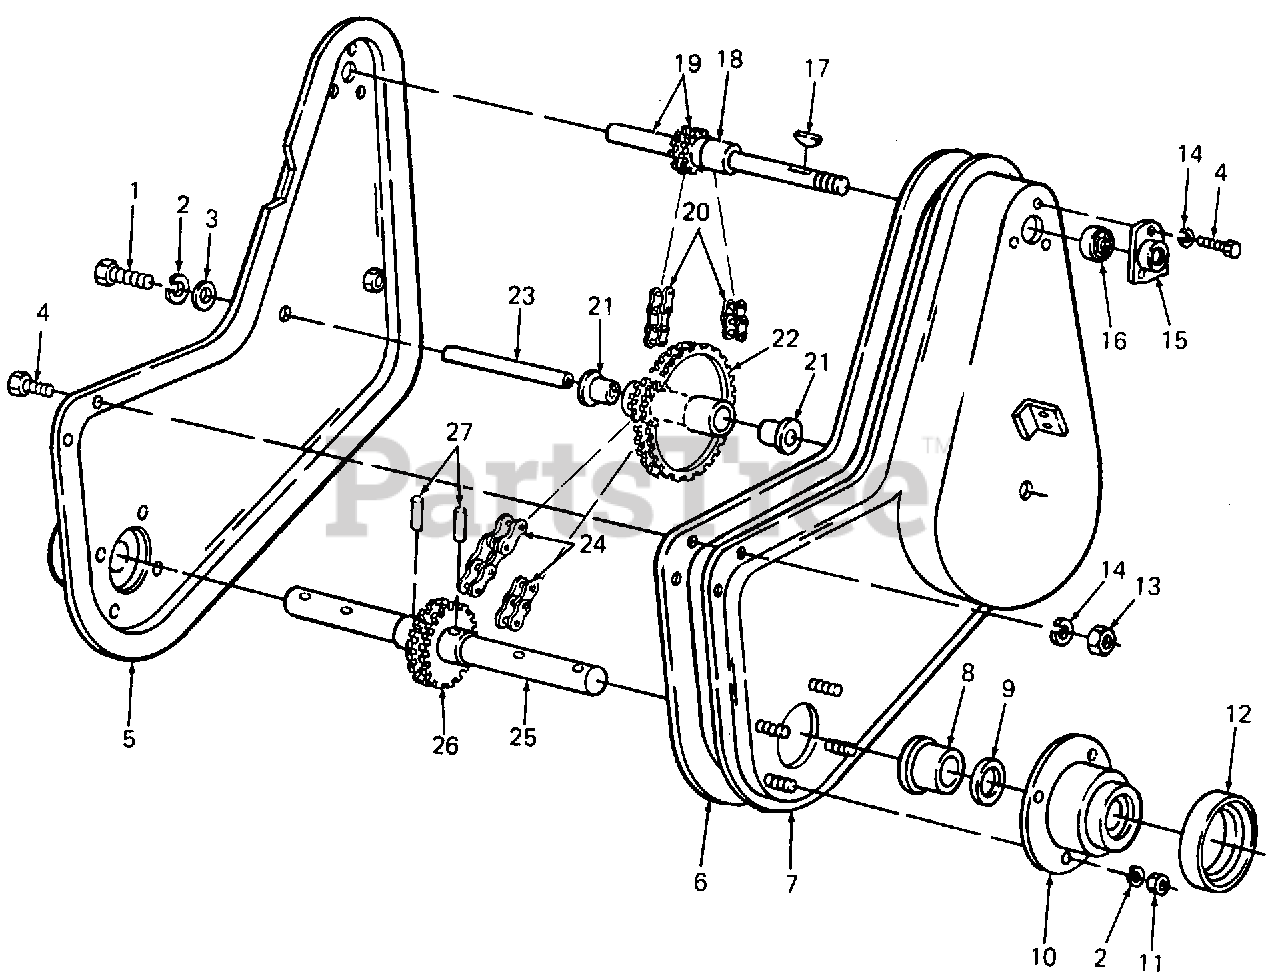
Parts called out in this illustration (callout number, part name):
1	Screw, Hex Cap, 5/16-18 X .75 Lg
2	Washer, Lock, 5/16
3	Washer, Flat, .344 X .88 X .040 Thk
4	Screw, Hex Cap, 1/4-20 X .62 Lg
9	Seal, Oil
10	Housing, Cast Bearing
11	Nut, Hex Center Lock, 5/16-18
12	Cover, Dust Cap
13	Nut, Hex, 1/4-20
14	Washer, Lock, 1/4
15	Housing, Bearing
16	Ball Bearing
17	Key, #6 Hi Pro, 5/32 X 5/8
19	Shaft Assy, Input w/Sprocket
20	Chain Assy, #35-2 3/8 Pitch X 97 Links
21	Bearing, Flange
22	Sprocket Assy, Double
23	Shaft, Sprocket
24	Chain Assy, #40-2 1/2 Pitch X 67 Links
25	Shaft, Tine
26	Sprocket Assy
27	Pin, Hvy Duty Spirol Spring, 3/8 X 2.0 Lg
